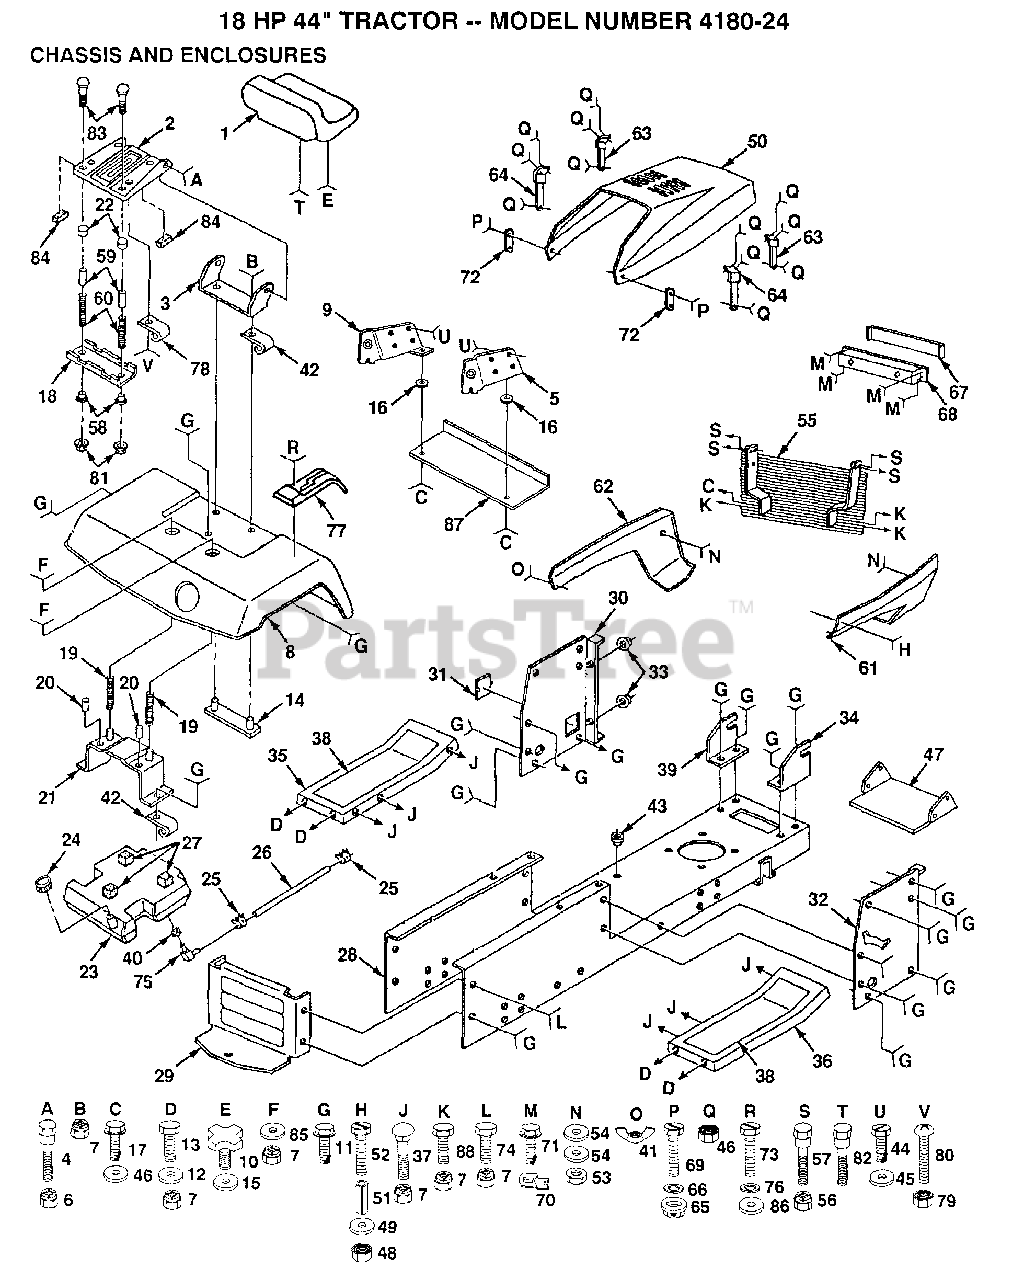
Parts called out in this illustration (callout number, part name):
5	SUPPORT RH YTH
8	FENDER
9	SUPPORT LH YTH
10	"KNOB 1/2"" YT"
11	SCREW
12	WASHER
15	WASHER
16	WASHER
17	SCREW
18	BRKT SWITCH
19	SPRING COMPRESSIO
20	NUT-PUSH YT
22	CAP SPRING
25	HOSE CLAMP
26	FUEL LINE T
27	PAD-SPACER LT
28	CHASSIS
29	DRAW BAR
30	PANEL DASH LH
31	COVER ACCESS
32	DASH PANEL RH
33	SNAP BUSHING T
34	SUPPORT RH YTH
37	BOLT
38	FOOTREST PAD
39	SUPPORT LH YTH
40	BUSHING OUTLET T
42	CLIP T
44	SCREW
45	WASHER
46	WASHER
47	"SHIELD,HEAT"
49	WASHER
51	SPACER LT
52	SCREW
54	WASHER PM
58	BUSHING
59	SPACER SPLIT
60	SPRING COMPRESSED
62	SIDE PANEL LH
65	WELDNUT
66	LOCKWASHER
67	LENS LT
69	SCREW
70	"""J"" FASTENER LT"
72	HOOD LATCH T
73	SCREW
75	FUEL TANK STEM GT
76	"WASHER,LOCK"
77	CONSOLE SHIFTER
79	"NUT,KEPS"
82	"BOLT,SHOULDER"
84	STRIP FORM
85	WASHER
86	WASHER
88	BOLT
89	NUT
